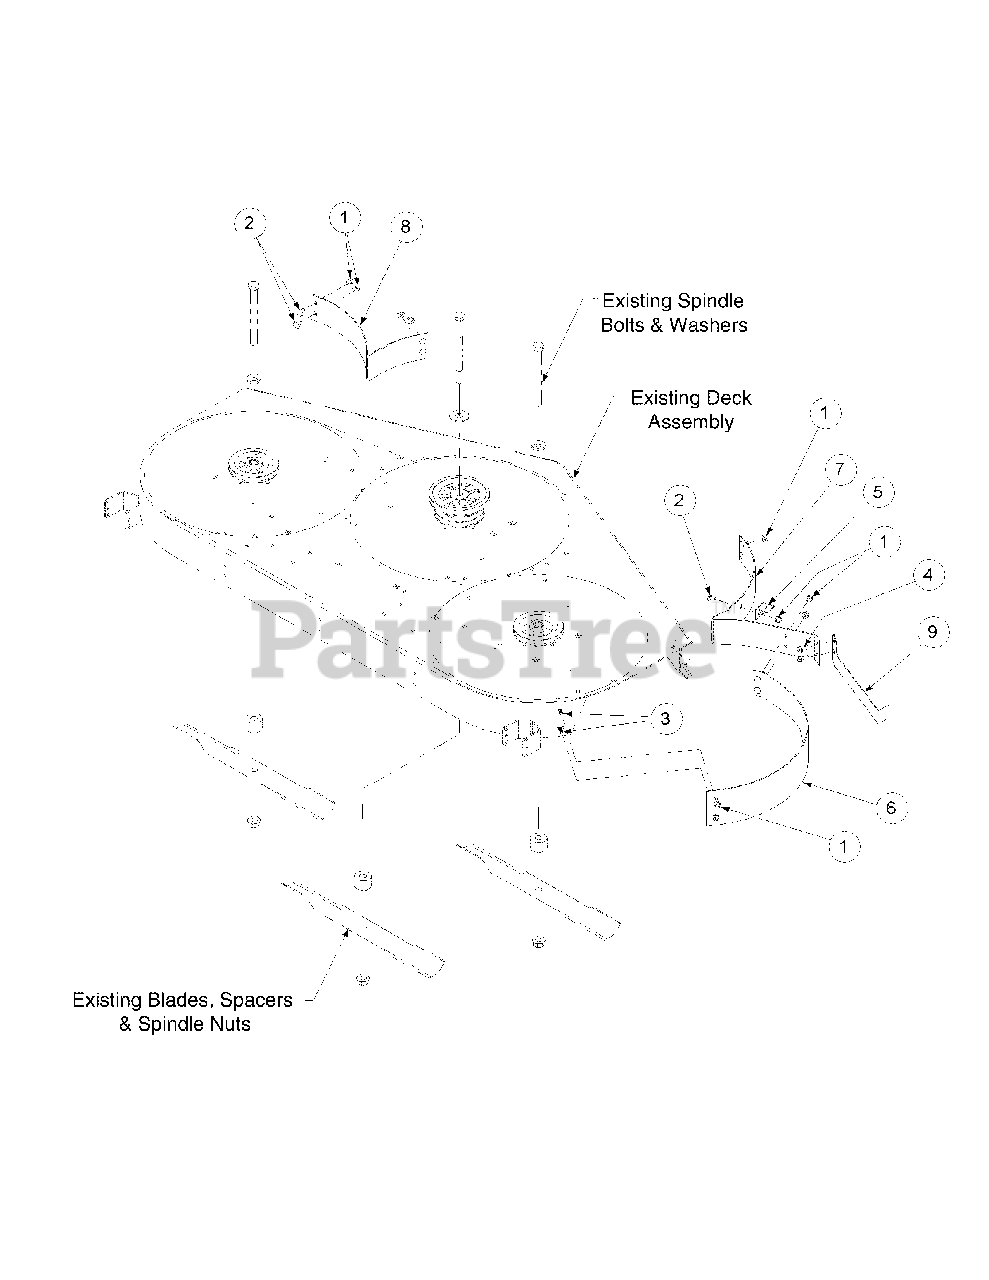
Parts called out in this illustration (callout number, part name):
1	Hex Nut, 3/8-16 Flange Lock
2	Carriage Bolt, 3/8-16 x .75
3	Carriage Bolt, 3/8-16 x 1.00
4	Self Tapping Screws, 3/8-16 x .875
5	Mulching Bracket Assembly
6	Mulching Baffle, RH
7	Mulching Baffle, Center
8	Mulching Baffle, LH
9	Deflector Baffle
